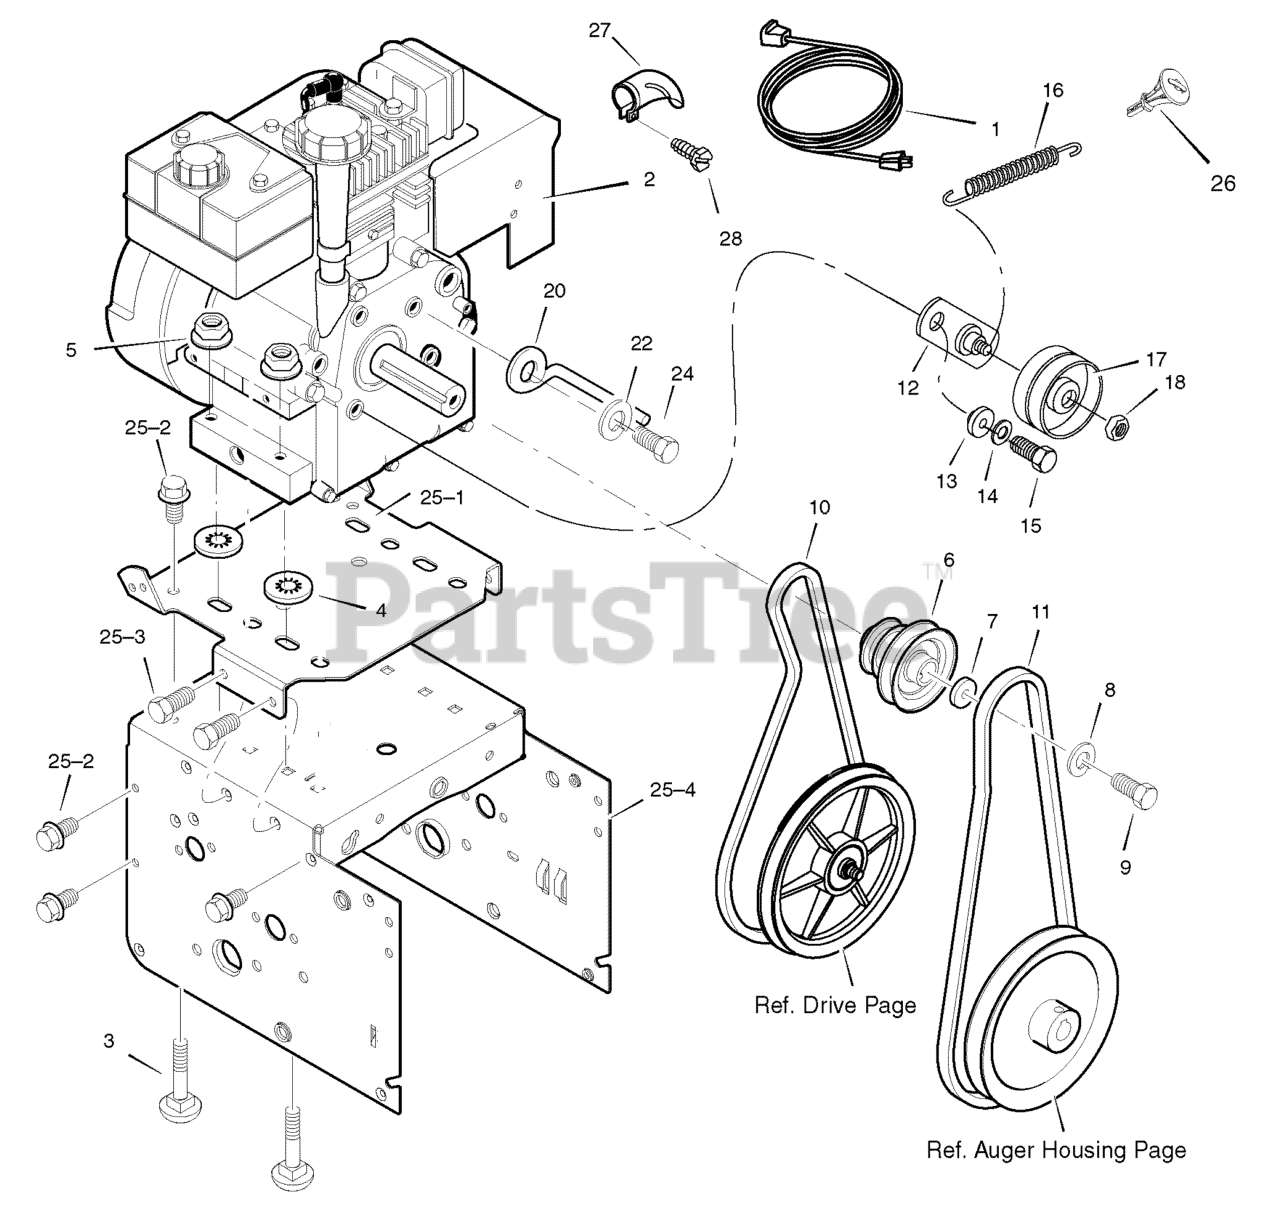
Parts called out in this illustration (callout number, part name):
1	CORD, Electric, 10FT. 110V
2	ENGINE
3	BOLT, CARRIAGE 5/16-18
4	RETAINER, PUSH
5	NUT 5/16-18
6	PULLEY, ENGINE
7	WASHER
8	WASHER
9	SCREW, .31-24 X 1.00
10	V-BELT, 3L, 33.13
11	V-BELT, 4L, 38.35
12	BRACKET ASSEMBLY, IDLER
13	BUSHING, IDLER BRACKET
14	WASHER
15	SCREW 5/16-24 X 0.75
17	PULLEY, IDLER
18	NUT, JAM 3/8-16
20	GUIDE, ROD BELT
22	WASHER, SPTLK .31 X .58 X .08
24	SCREW, 5/16-24 X 0.75
25	FRAME ASSEMBLY
25-1	PLATE, ENGINE MOUNT
25-2	SCREW 1/4-20 X .63
25-3	SCREW 5/16-18 X .50
25-4	FRAME, MOTOR BOX
26	KEY, IGNITION
27	DEFLECTOR, Muffler
